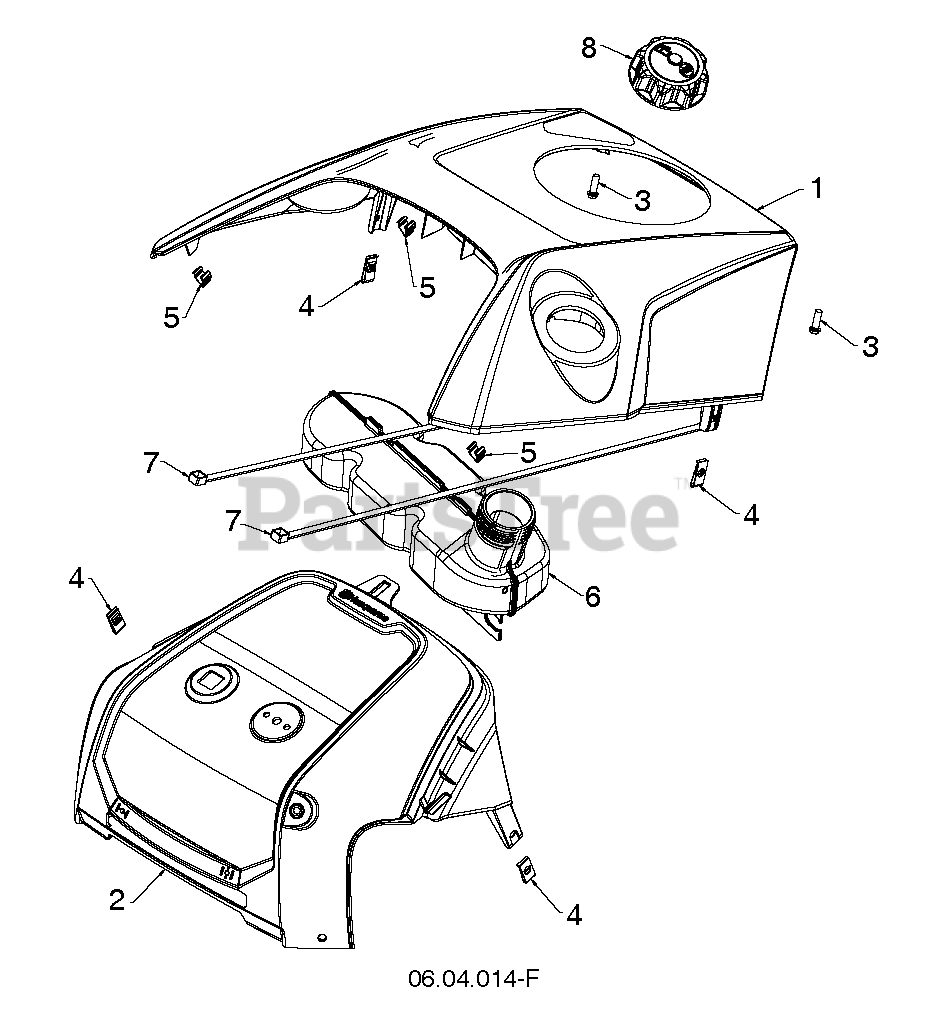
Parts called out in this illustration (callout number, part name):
1	COVER TOP.COVER
2	COVER.REAR.UPPER.SSST.HUSQ
3	SCREW.HX.13X.750
6	TANK.GAS.12.SINGLE.STAGE.SNOW
7	TIE.CABLE.24.5X.29.NYLON.WHITE
8	CAP.2.25'.VENTED.RATCHET.EPA
